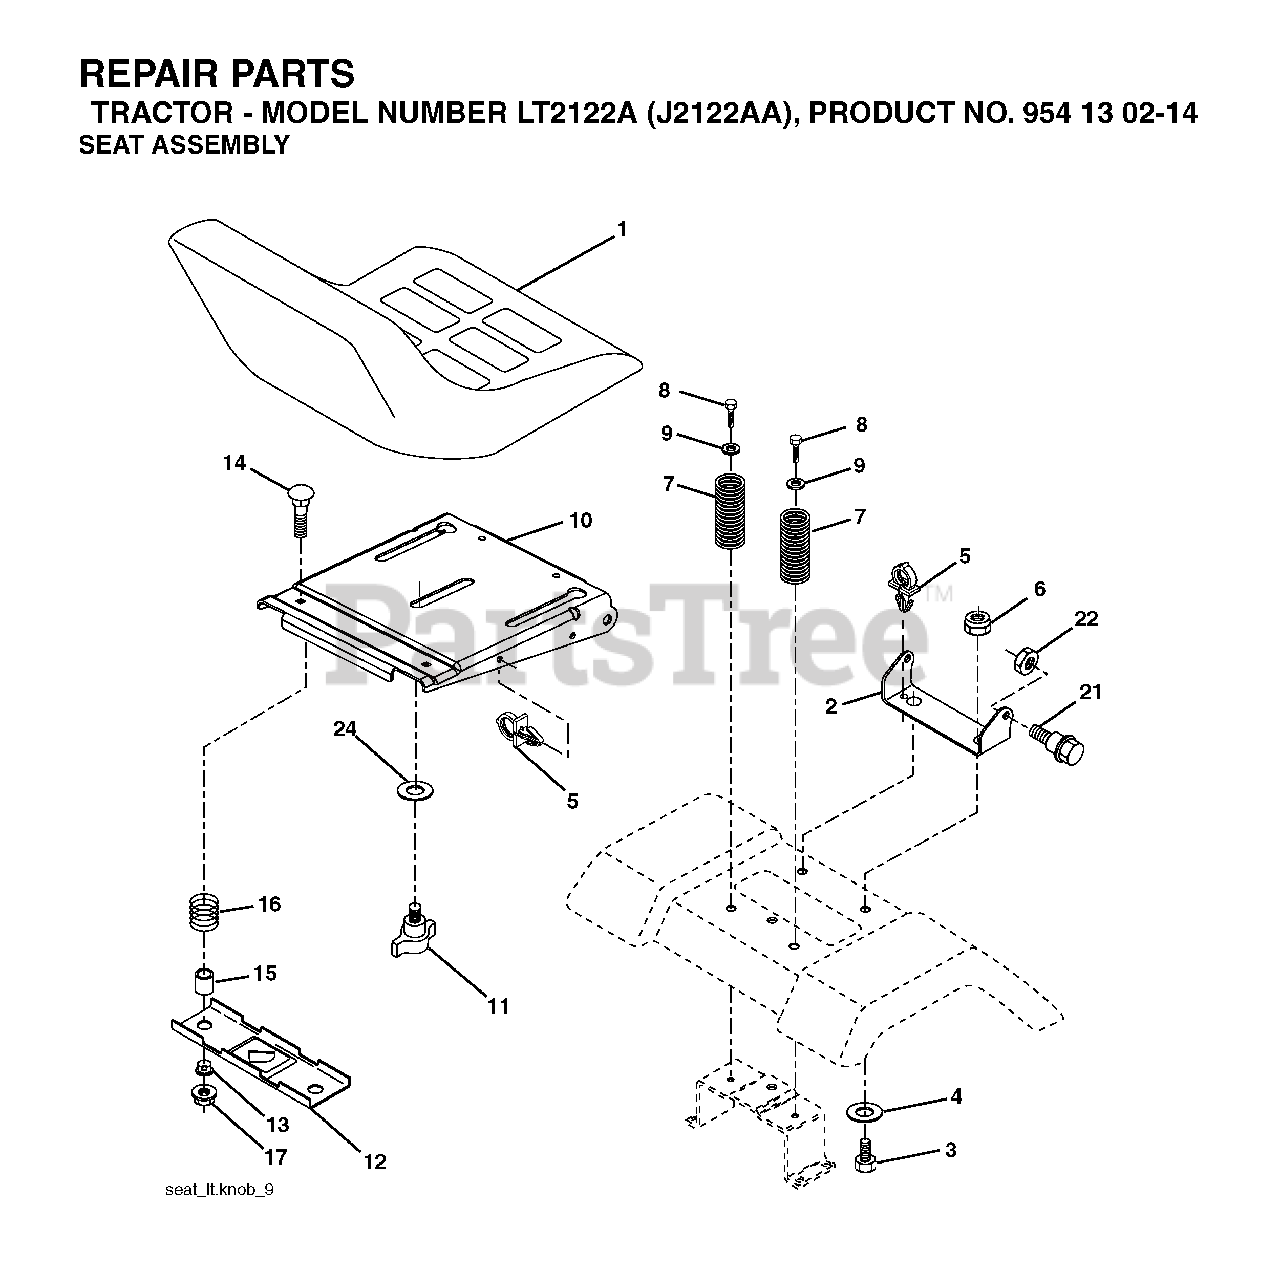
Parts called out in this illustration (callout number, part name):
2	BRKT.PIVOT.FENDER
4	WASHER PM
5	PUSH CLIP
6	NUT
7	SPRING COMPRESSION
8	SCREW 3/8-16X1
9	WASHER
11	KNOB.SEAT.ADJ.WINGNUT
12	BRKT SWITCH
14	BOLT.ROUND.HEAD.SQUARE.NECK
15	SPACER SPLIT
16	SPRING COMPRESSED
17	NUT T
21	BOLT.SHOULDER.5/16-18
22	NUT.71038.31-18.HEX.NYLOCK
